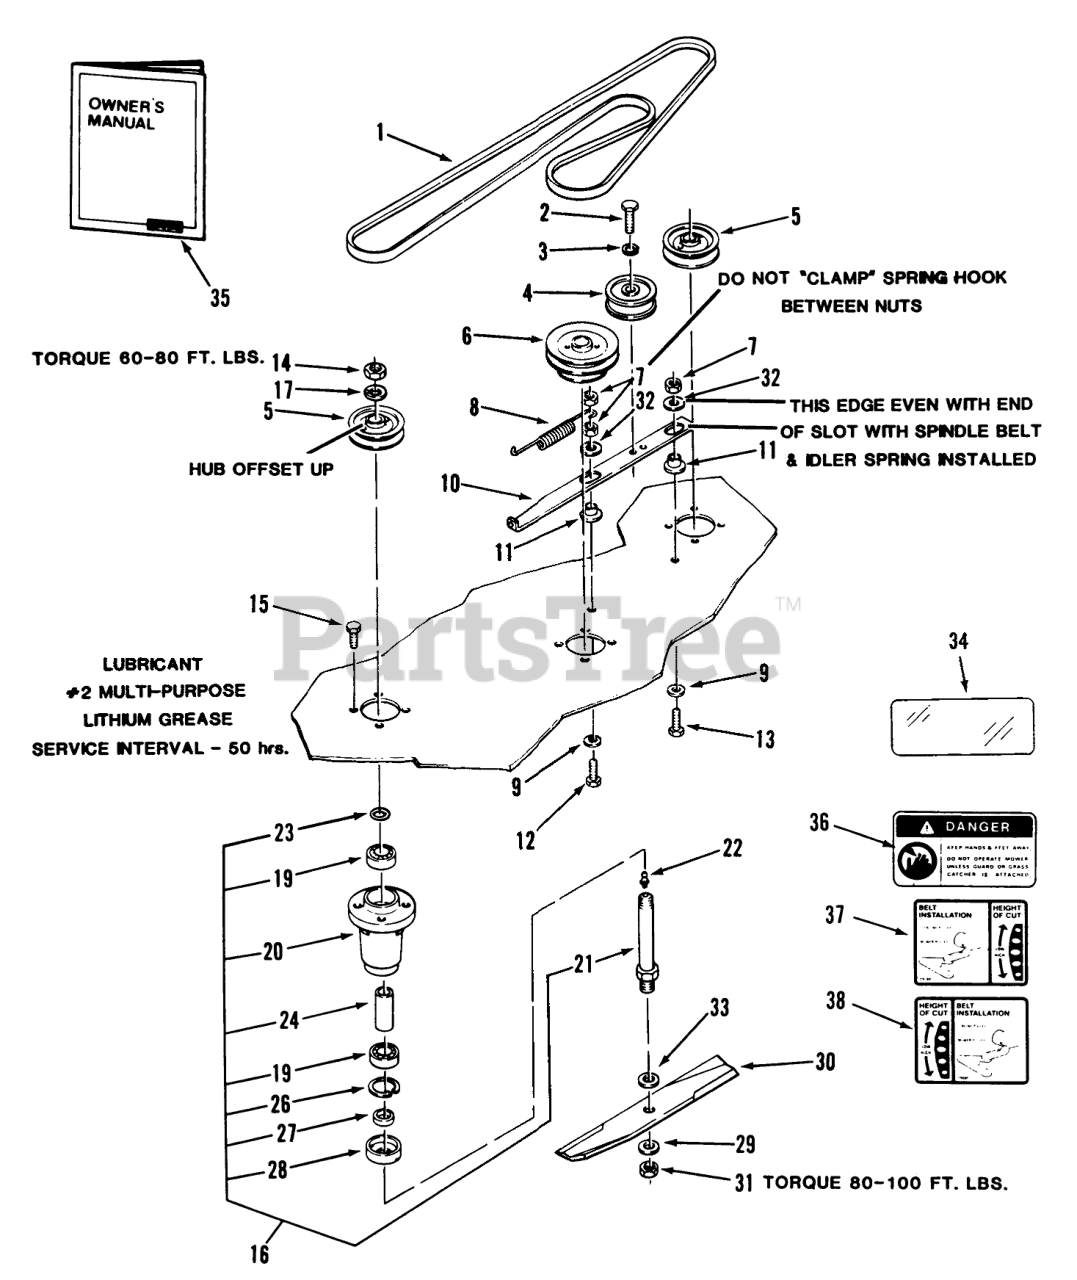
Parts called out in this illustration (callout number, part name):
1	V BELT
1	V-BELT
2	BOLT HEX SPECIAL
2	Bolt
3	LOCKWASHER
4	Idler Pulley
4	Pulley
5	PULLEY
5	PULLEY-BLADE, DRIVE
6	PULLEY
6	PULLEY-MOWER, 48IN
7	NUT
8	SPRING-EXTENSION
9	WASHER
10	BAR-IDLER SUPPORT
11	SPACER-BUSHING
12	Bolt
13	Bolt
14	Jam Nut
15	Bolt
16	Spindle Assembly
17	Lockwasher
19	BEARING-BALL
20	HOUSING-SPINDLE
21	SHAFT-SPINDLE
22	Zerk
23	O RING
26	Ring-Snap
27	SPACER-BLADE
28	CUP-SPINDLE
29	SpeciaI Washer
29	Washer
30	14IN BLADE KIT
30	BLADE KIT (3 PACK)
30	BLADE KIT
31	Nut-Jam
32	WASHER
33	Washer
33	SpeciaI Washer
34	DECAL-OVERLAY
35	Manual-Operators
36	Danger Decal
37	DECAL-HEIGHT & BELT
38	DECAL-HEIGHT & BELT
